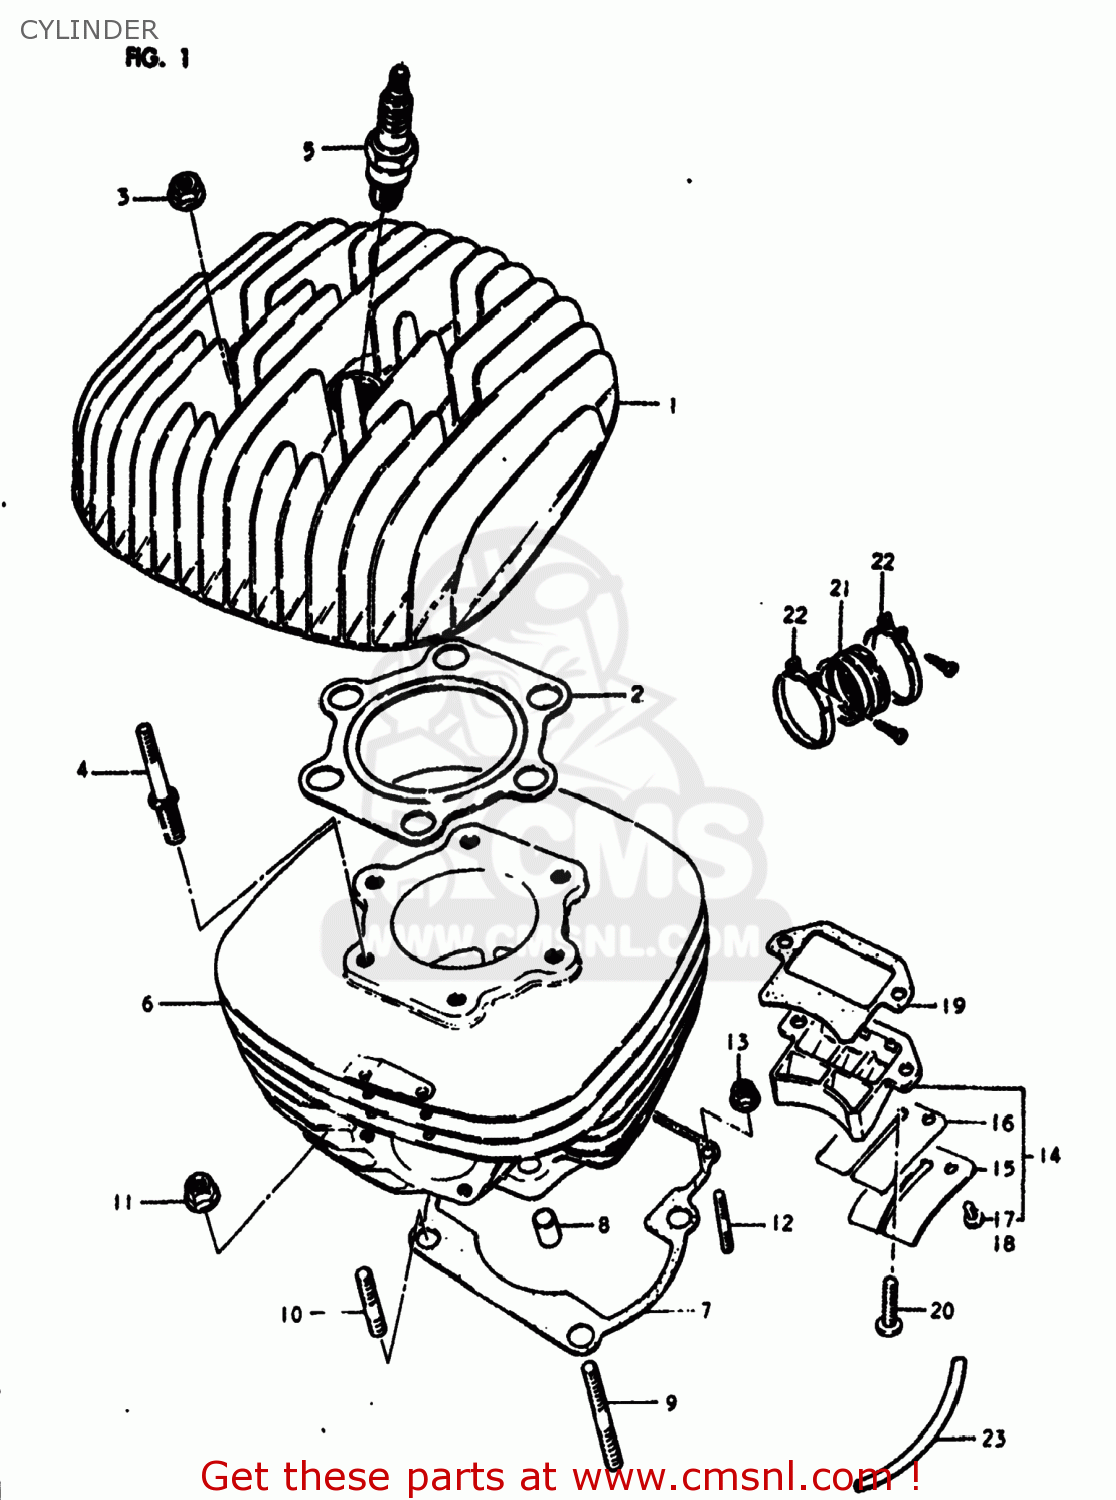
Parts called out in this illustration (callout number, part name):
1	HEAD,CYLINDER
2	GASKET,CYLINDER HEAD (NAS)
3	NUT
4	BOLT,STUD
5	SPARK PLUG N-2G CHMP
6	CYLINDER
7	GASKET,CYLINDER (MCA)
8	PIN
9	STUD BOLT (L:40)
10	STUD 10X25
11	NUT
12	STUD 6X20
13	NUT
14	VALVE ASSEMBLY,REED
15	STOPPER,REED VALVE
16	VALVE,REED
17	SCREW
18	LOCK WASHER
19	GASKET,REED VALVE (MCA)
20	SCREW
21	PIPE,INTAKE
22	CLAMP
23	HOSE
